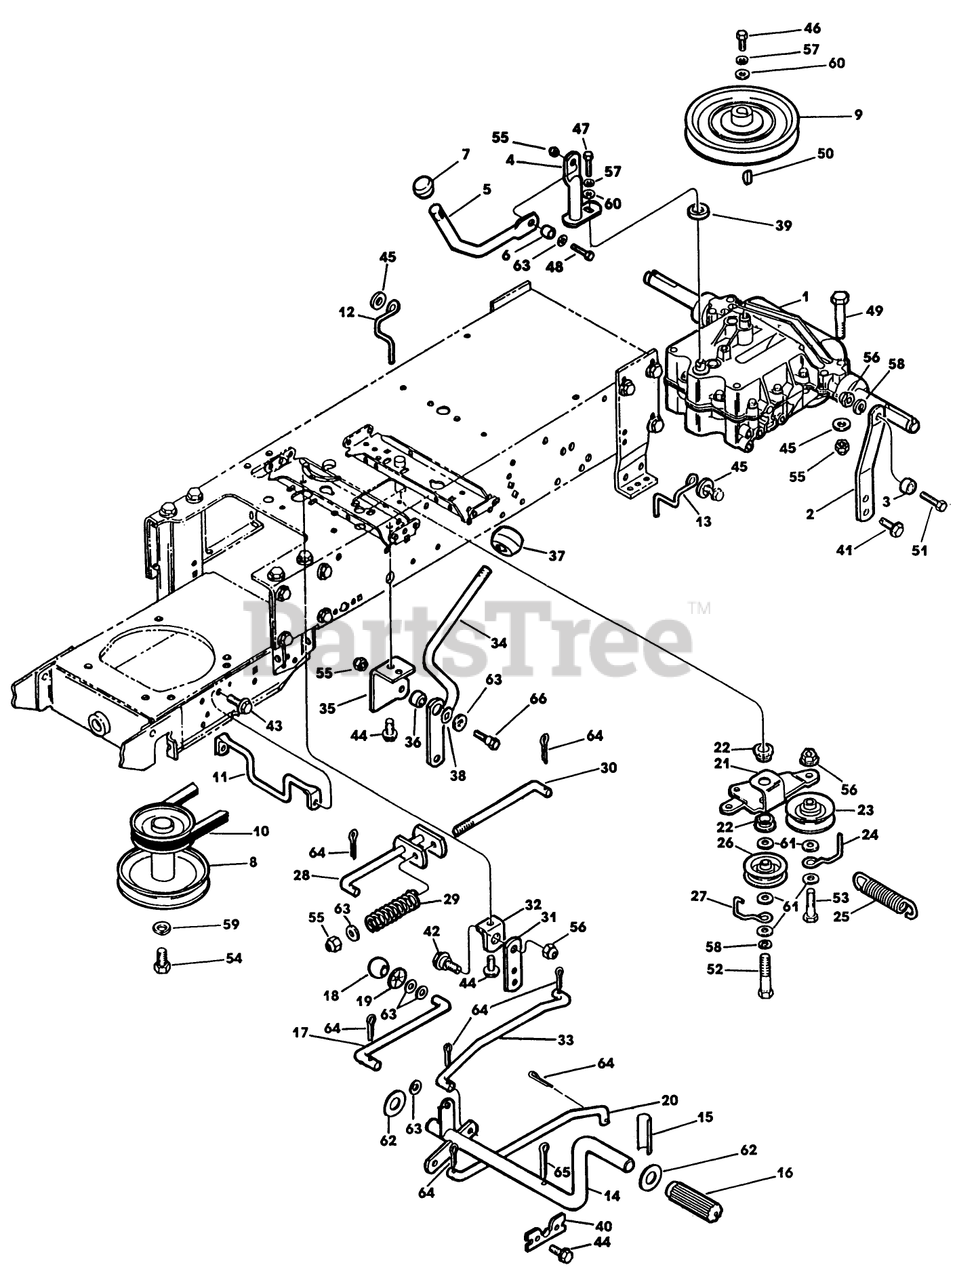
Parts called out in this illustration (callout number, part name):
8	PULLEY - ENGINE
9	PULLEY-TRANSMISSN
10	V-BELT
11	GUIDE
12	FINGER-BELT
13	FINGER-BELT
16	GRIP - FOOT PEDAL
23	PULLEY-IDLER "V"
25	SPRING
27	RETAINER-BELT
31	LINK - BRAKE
47	SCREW-HEXHEAD
55	NUT
56	NUT-LOCKING
58	WASHER
60	WASHER
61	WASHER
66	SCREW
